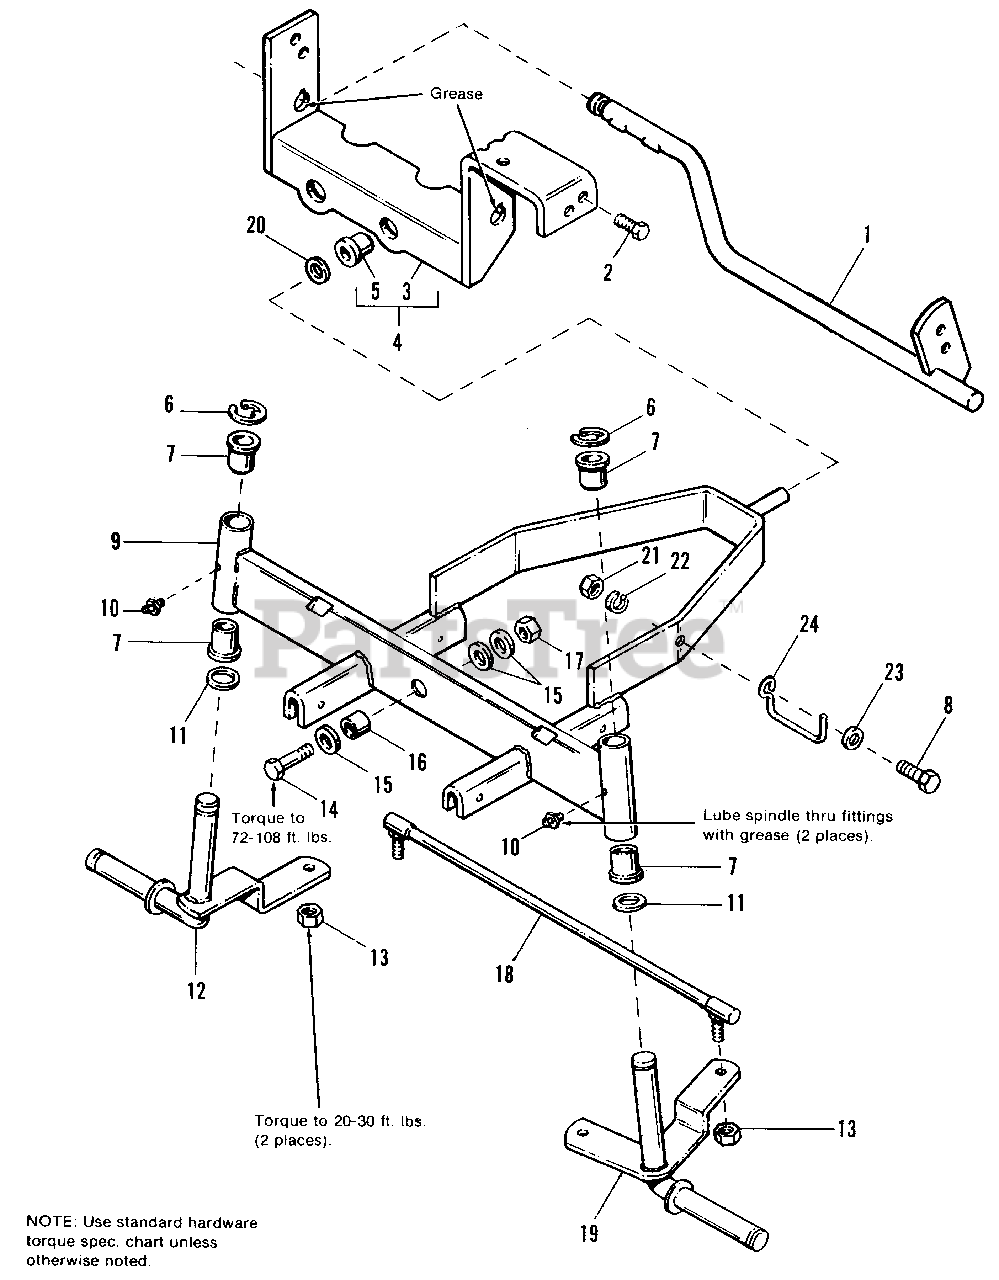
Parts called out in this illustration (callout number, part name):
1	LEVER ASSY., Brake
2	SCREW, Taptite, 5/16-18 x 3/4
4	SUPPORT ASSY., Rear
6	"E" RING, Ext. 3/4
8	CAPSCREW, Hex, 5/16-18 x 1
9	AXLE ASSY., Front
10	FITTING, Lube, 1/4-20
12	SPINDLE ASSY., R.H.
13	LOCKNUT, Hex, 3/8-24, Gr. 8
14	CAPSCREW, Hex, 1/2-13 x 1-3/4, Gr. 8
15	WASHER, 9/16
16	SPACER
17	LOCKNUT, Hex, 1/2-13
18	TIE ROD ASSY.
19	SPINDLE ASSY., L.H.
20	WASHER, 5/8
21	NUT, Hex, 5/16-18
22	LOCKWASHER, 5/16
23	WASHER, 5/16
24	GUIDE, Drag Link
